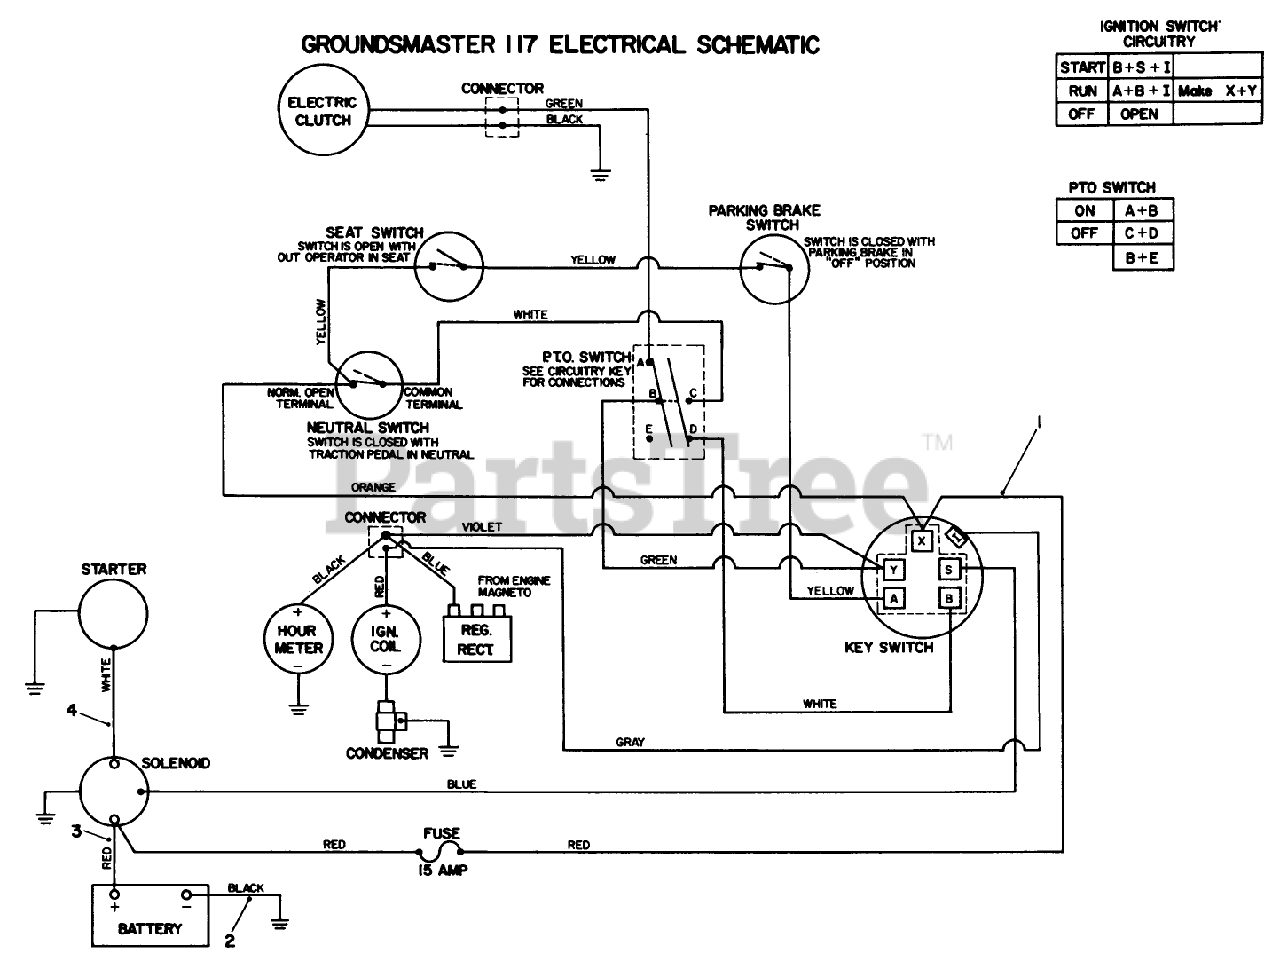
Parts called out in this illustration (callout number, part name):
1	WIRE HARNESS
2	BATTERY/GROUND WIRE
3	WIRE ASM
4	WIRE ASM
